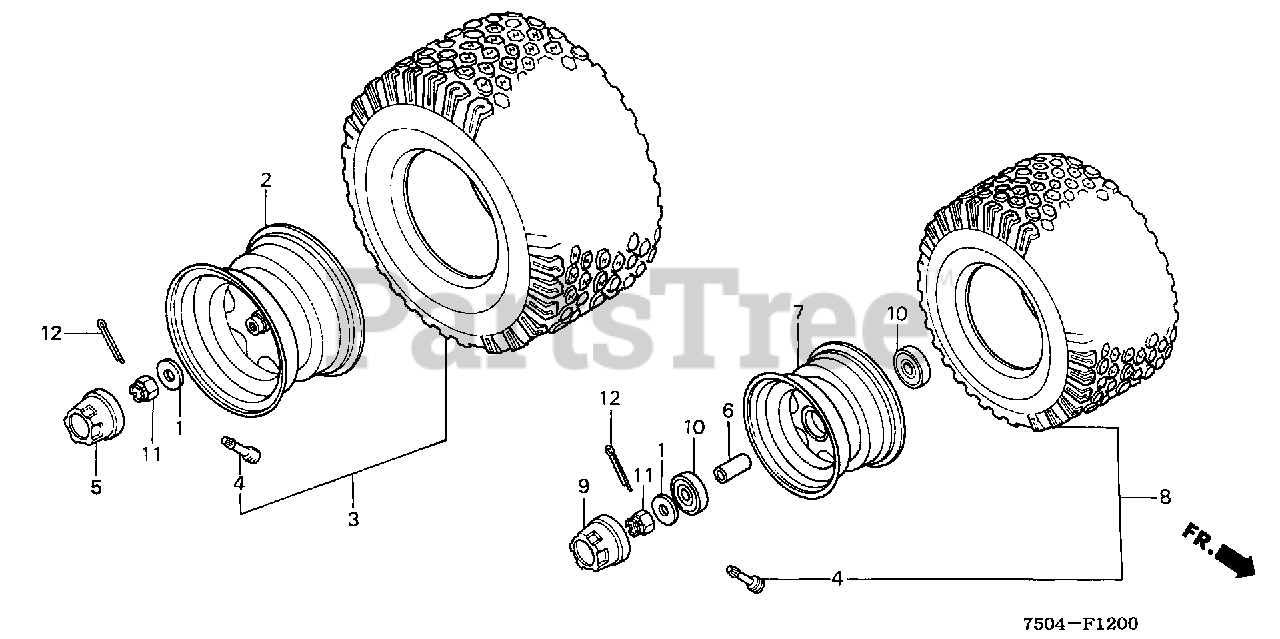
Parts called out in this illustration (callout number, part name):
1	WASHER (14MM)
2	WHEEL *NH35M* (CLOUD SILVER METALLIC) (NOT AVAILABLE)
3	TIRE ASSY., RR.
4	VALVE, RIM (BS)
4	VALVE, RIM (TAIHEIYO)
5	CAP, RR. HUB
6	COLLAR, FR. AXLE DISTANCE
7	WHEEL *NH35M* (CLOUD SILVER METALLIC) (NOT AVAILABLE)
8	TIRE ASSY., FR.
9	CAP, FR. HUB
10	BEARING, RADIAL BALL
11	NUT, CASTLE (14MM)
12	PIN, COTTER (3.0X45)
